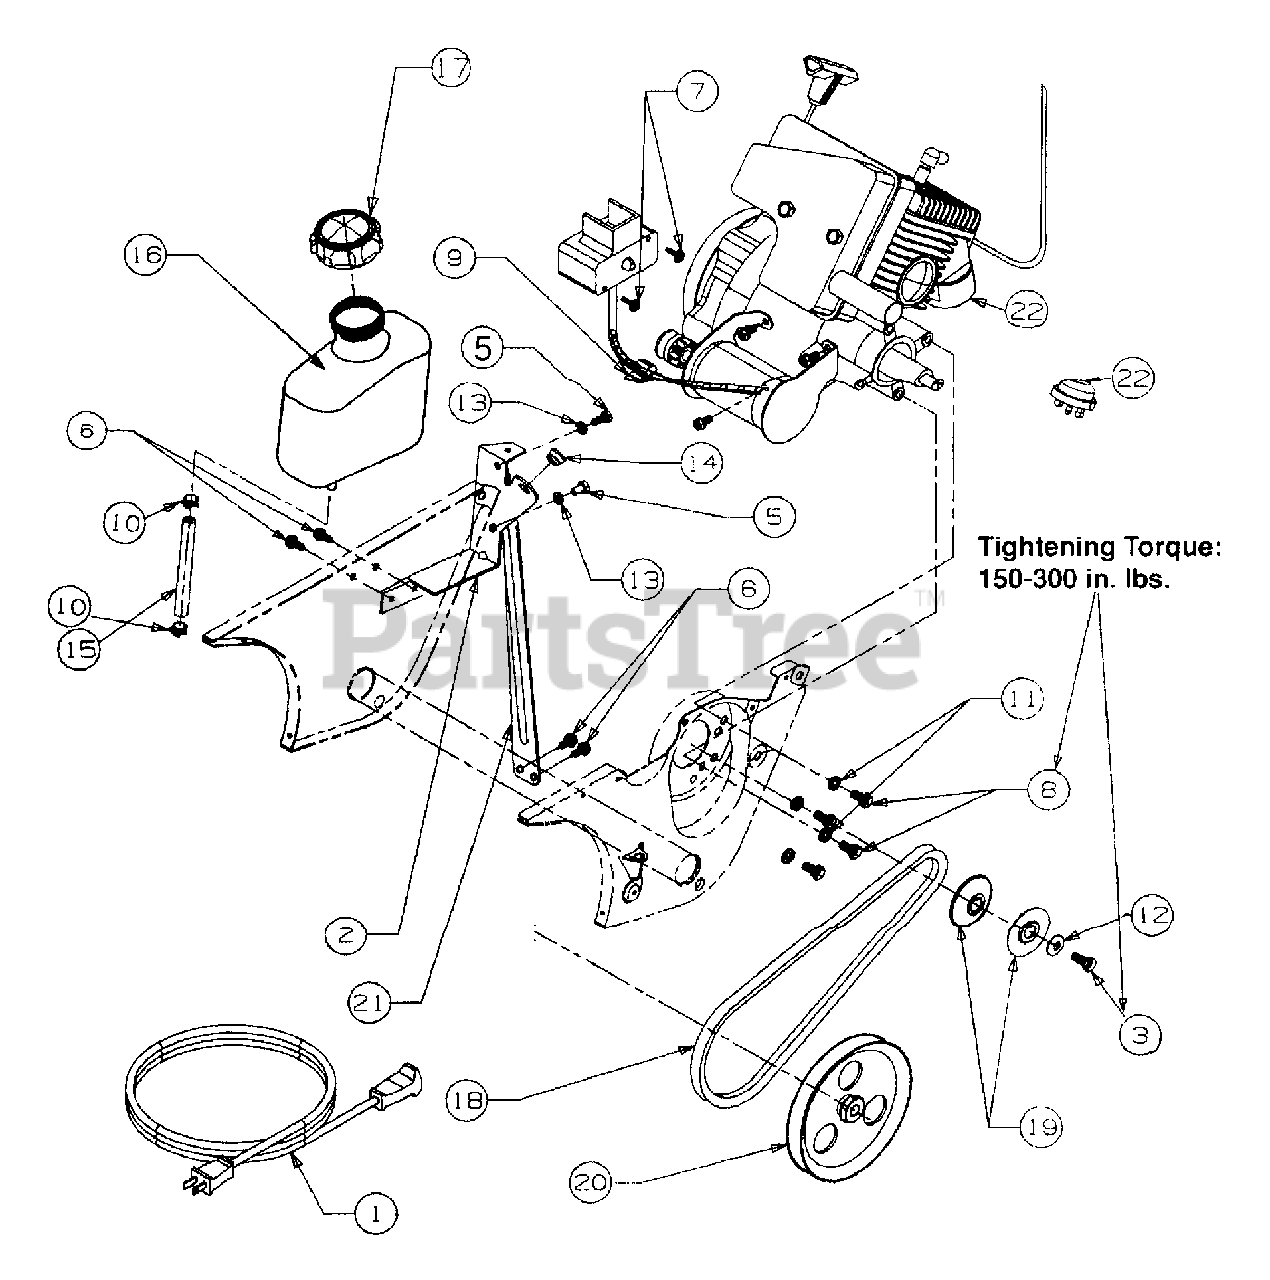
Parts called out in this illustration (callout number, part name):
1	Cord - Extension 110V3M 2 Prong
2	Bracket - Support Fuel Tank
3	Screw - Hex Cap
5	Screw - Hex
6	Screw - Washer
7	Screw - Hex
8	Screw - Hex Cap
9	Clamp - Mounting
10	Clamp - Hose
11	Washer - Lock
12	Washer - Bell
13	Washer - Lock
14	Bushing - Plastic
15	Hose - Fuel Line 16"
16	Tank - Fuel 2 Qt.
17	Cap - Fuel - Black Letters
18	V-Belt
19	V-Pulley Half
20	Pulley
22	Obtain from Engine Manufacturer
